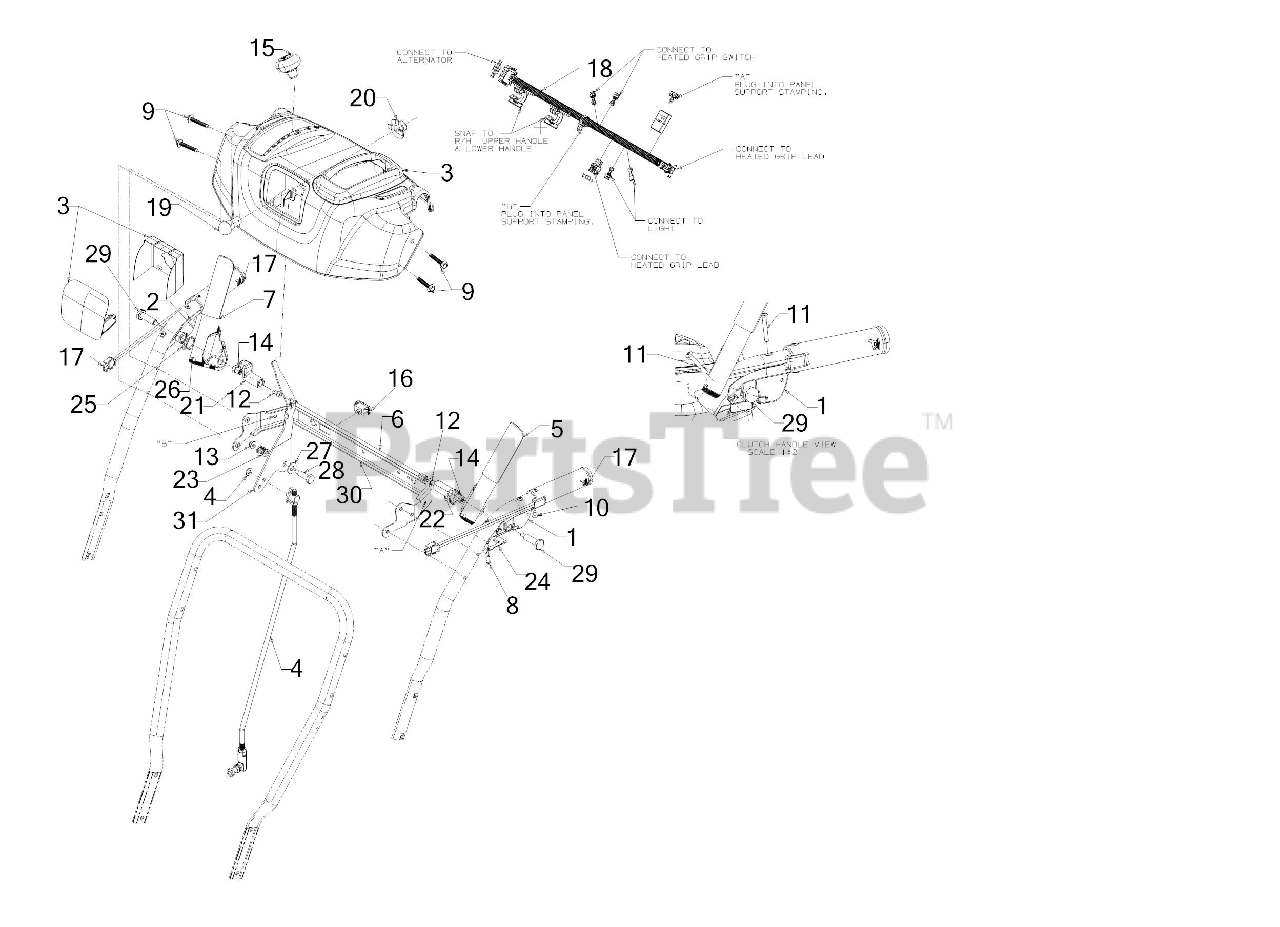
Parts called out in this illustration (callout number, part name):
1	CLUTCH LOCK HANDLE ASSEMBLY (LH)
2	CLUTCH LOCK HANDLE ASSEMBLY (RH)
3	HANDLE PANEL ASSEMBLY (BLACK)
4	SHIFT ROD ASSEMBLY
5	HANDLE ASSEMBLY (LH)
6	PIVOT ROD
7	HANDLE ASSEMBLY (RH)
8	SCREW #8-16 x .50
9	SCREW 1/4-20 x 1.625
10	SCREW #10-16 x .625
11	SCREW #10-24 x 1.375
12	SCREW 1/4-20 x .50
13	FLANGE LOCK NUT
14	HEX NUT W/PATCH
15	SHIFT KNOB
16	HEATED GRIP SWITCH
17	HARNESS
18	HEATED GRIPS HARNESS
19	LAMP-12V
20	HEADLIGHT SOCKET
21	LOCK PLATE
22	CLUTCH LOCK CAM
23	COMPRESSION SPRING
24	CLUTCH SPRING
25	TORSION SPRING
26	RUBBER BUMPER
27	FLAT WASHER
28	SHOULDER SCREW
29	SHOULDER SCREW .437 x 1.345 1/4-20
31	SHIFT LEVER
